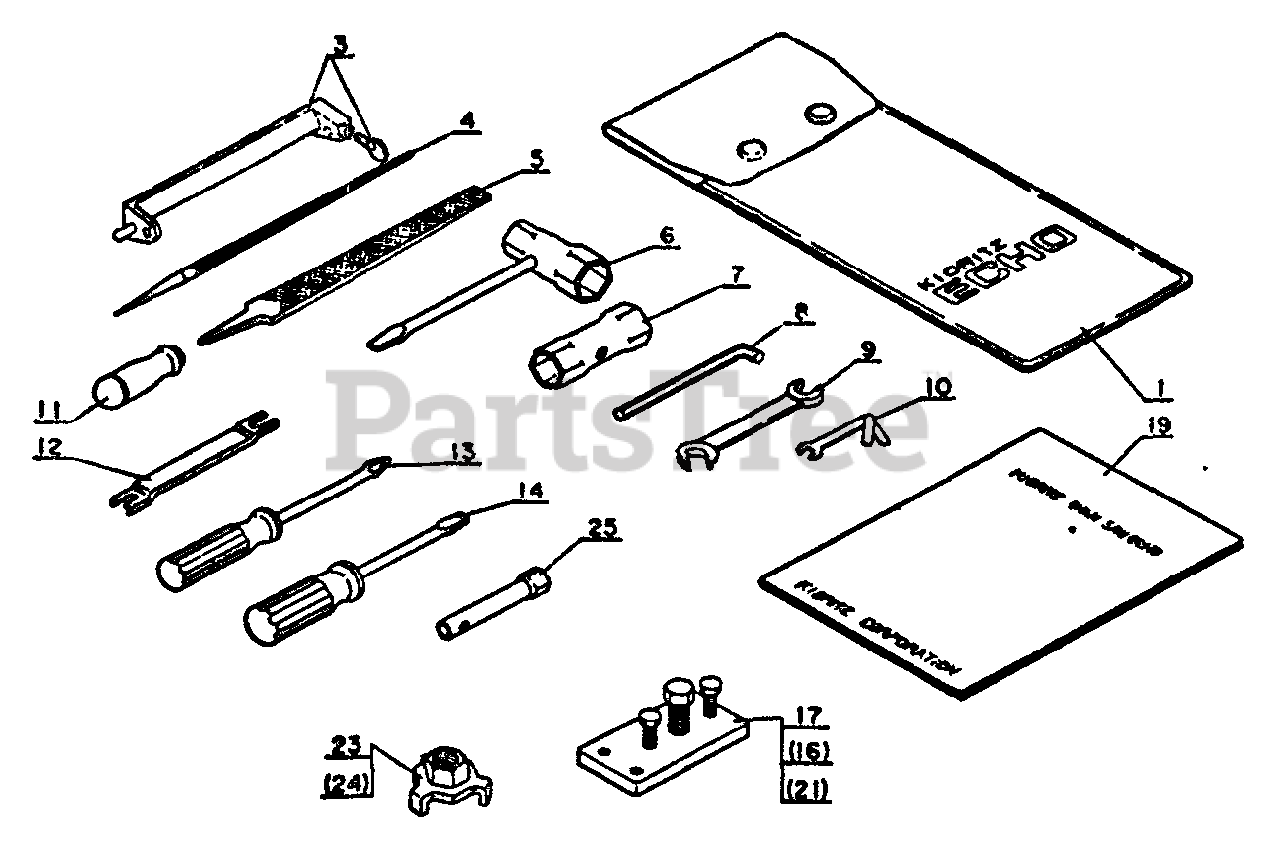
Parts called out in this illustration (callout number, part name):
1	BAG, TOOL
3	FILE HOLDER
4	FILE - ROUND
5	FILE - FLAT
6	T-WRENCH - 13X19mm
7	SOCKET WRENCH - 14X17mm
8	HEX KEY - 4mm
9	SPANNER - 8X10mm
10	Magneto spanner
11	FILE GRIP
12	DEPTH GAUGE
13	SCREWDRIVER - (+)
14	SCREWDRIVER
17	MAGNETO PULLER
19	Instruction manual
25	SOCKET WRENCH - 8mm
